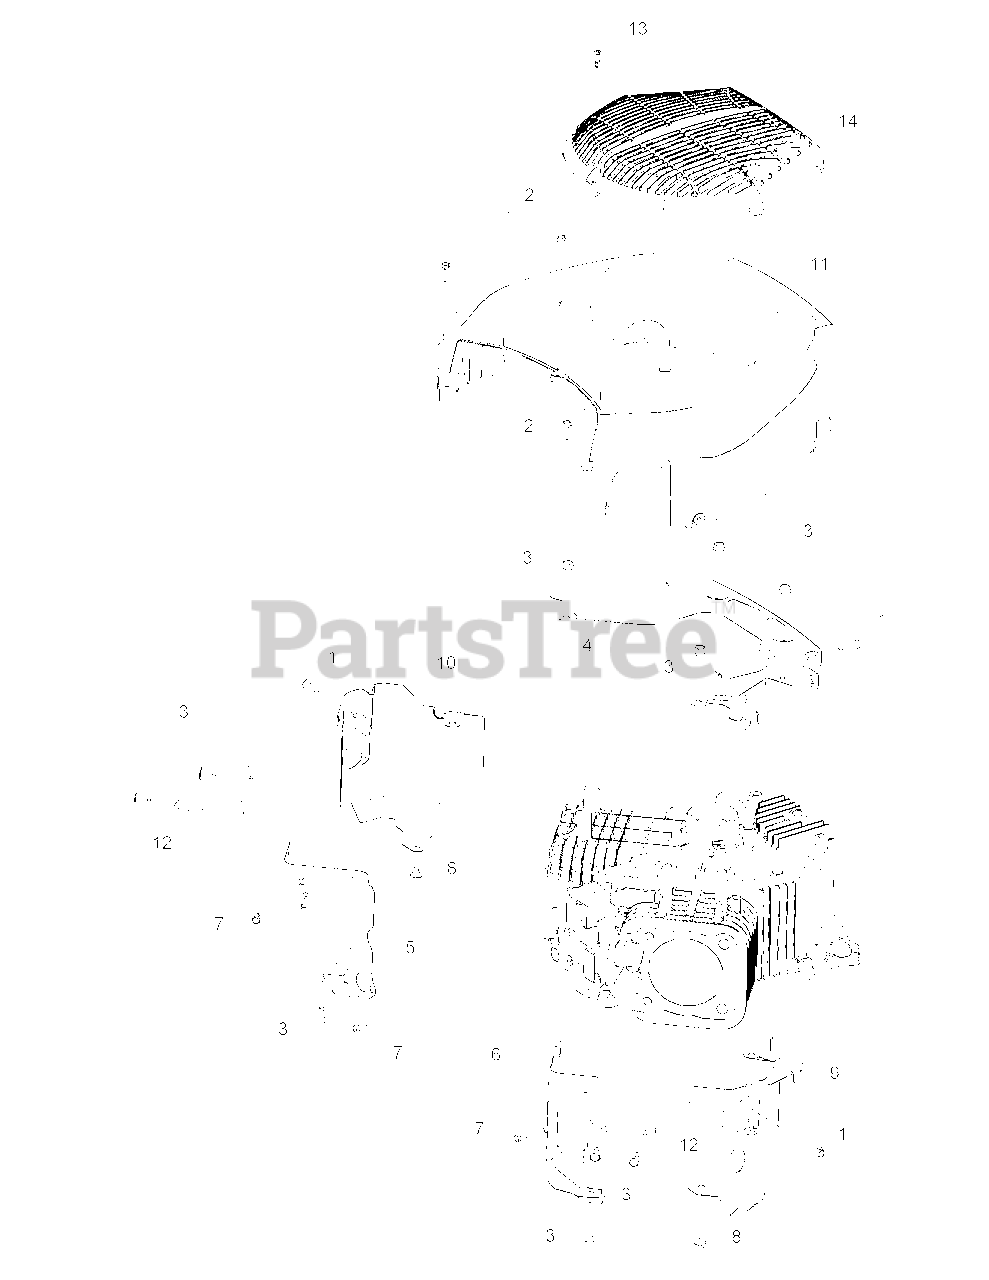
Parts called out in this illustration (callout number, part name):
1	Thread Forming Screw
3	Thread Forming Screw
4	Backing Plate
5	Valley Baffle, #1 Cylinder
6	Valley Baffle, #2 Cylinder
7	Thread Forming Screw
8	Thread Forming Screw
9	Left Barrel Baffle
10	Right Barrel Baffle
11	Blower Housing
13	Screw, M5-2.42
